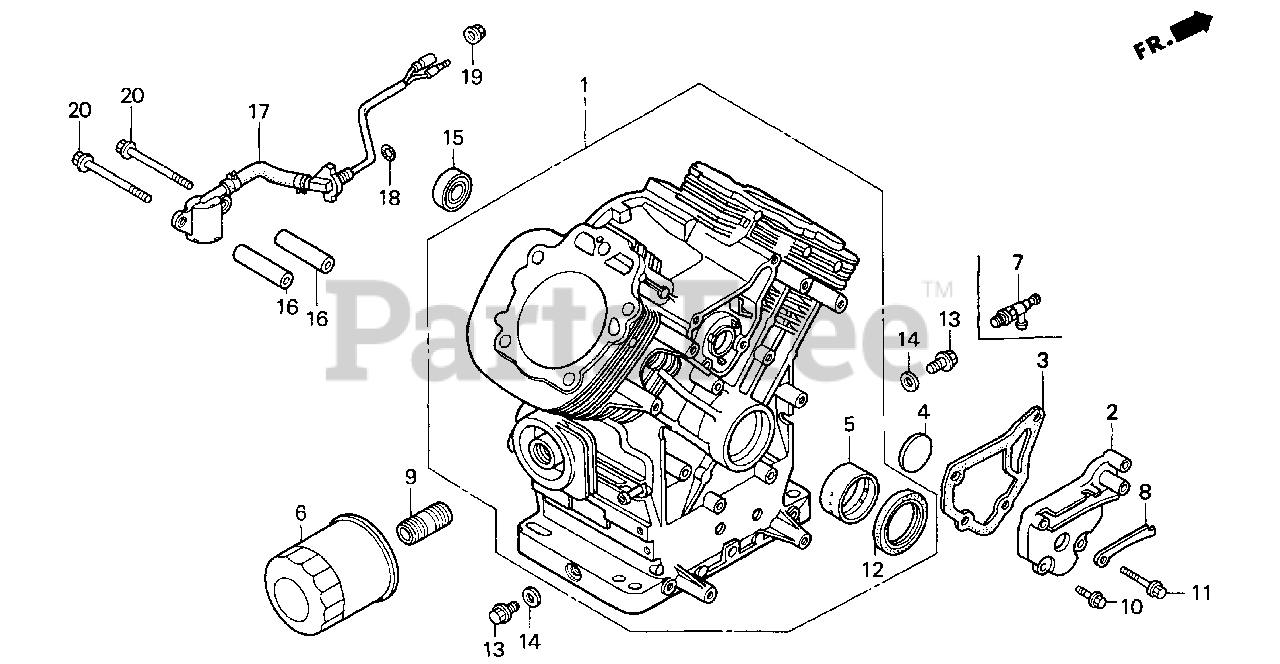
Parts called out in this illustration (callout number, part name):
1	CYLINDER ASSY.
2	COVER, BREATHER
3	GASKET, BREATHER COVER
4	VALVE, BREATHER
5	BEARING A, MAIN (TO SELECT CORRECT BEARING, SEE THE SERVICE MANUAL.)
5	BEARING B, MAIN (TO SELECT CORRECT BEARING, SEE THE SERVICE MANUAL.)
5	BEARING C, MAIN (TO SELECT CORRECT BEARING, SEE THE SERVICE MANUAL.)
6	FILTER, OIL (SOLD INDIVIDUALLY)
6	FILTER, OIL (SOLD IN MULTIPLES OF 30)
7	VALVE, DRAIN (14X1.5)
8	CLAMP, WIRE
9	HOLDER, OIL FILTER
10	BOLT, FLANGE (6X16)
11	BOLT, FLANGE (6X32)
12	OIL SEAL (38X58X11)
13	BOLT, DRAIN PLUG (14MM)
14	WASHER, DRAIN PLUG (14MM)
15	BEARING, RADIAL BALL (6003)
16	COLLAR, FILTER SETTING
17	SWITCH ASSY., OIL LEVEL
18	O-RING (13.5X1.5) (ARAI)
19	NUT, FLANGE (10MM)
20	BOLT, FLANGE (6X75)
